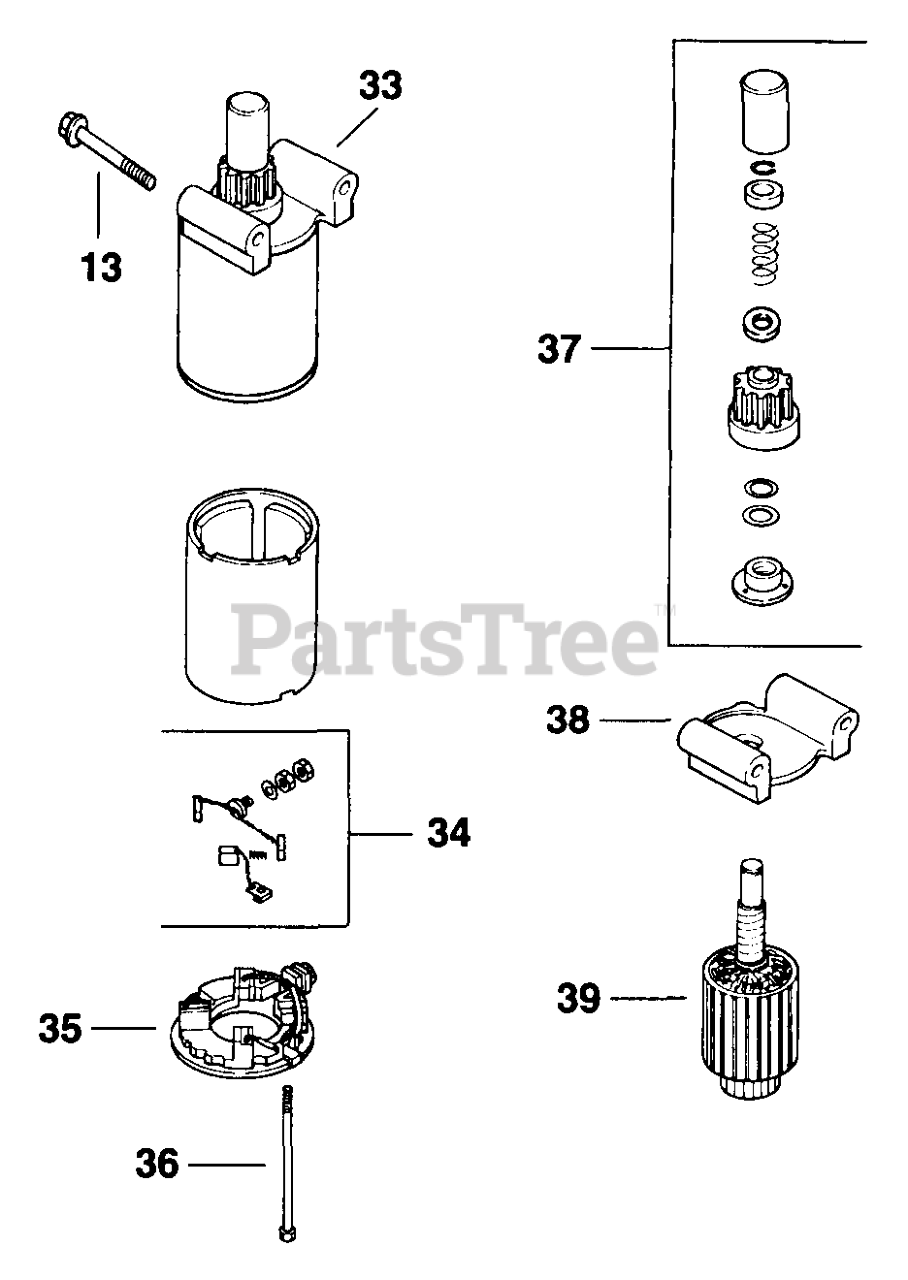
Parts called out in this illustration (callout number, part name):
13	SCREW - USE M-839070
34	KIT, BRUSH & SPRING - DISCONTINUED
35	COMMUTATOR, END CAP
36	SCREW - (#DSC)
37	KIT, DRIVE
39	ARMATURE ASSY - DISCONTINUED
